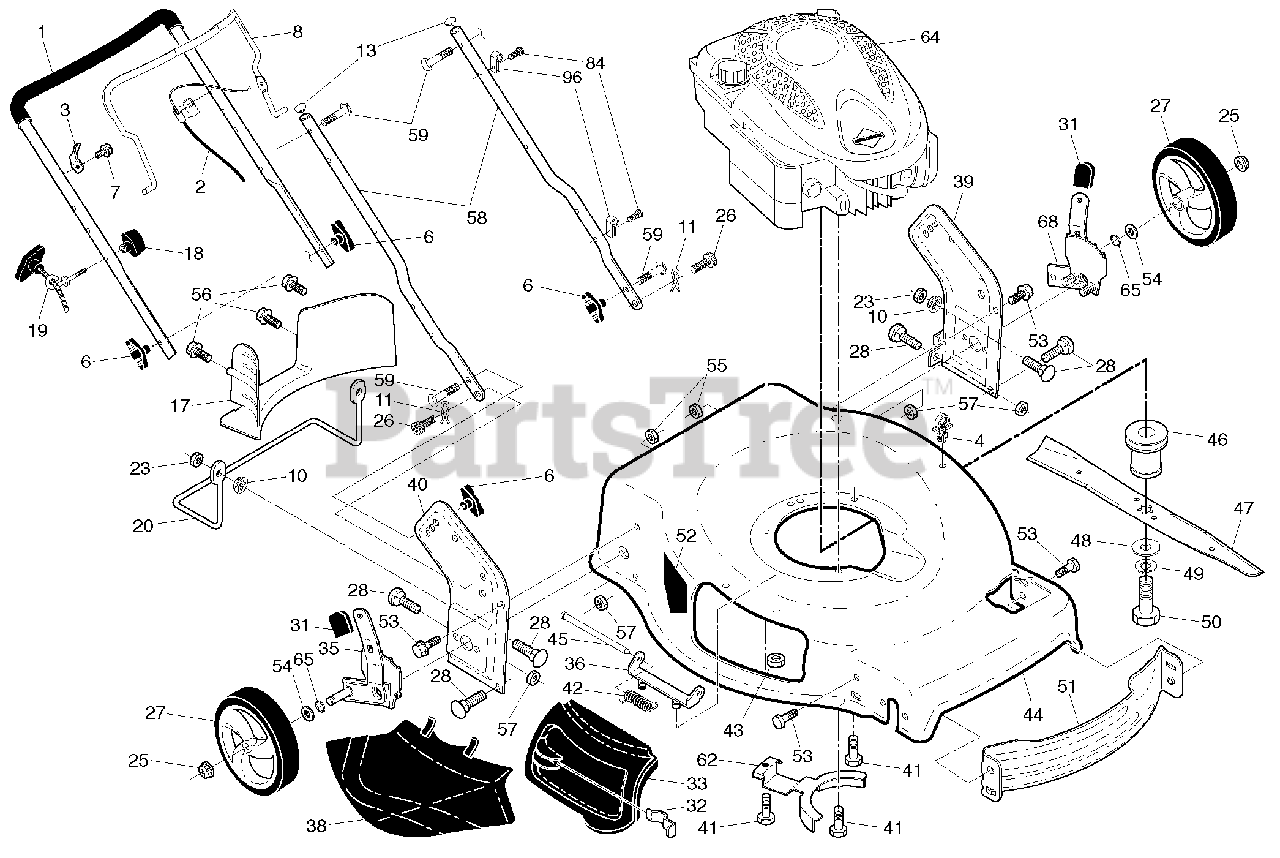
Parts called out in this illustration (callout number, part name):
1	HANDLE.ASM.UP.BS.PU/SS.GRP.479
2	Cable, MZR Fgd 22+ Ergo
3	BRACKET.UPSTOP.RT
4	PUSH CLIP
6	KNOB, DEFLECTOR
11	COTTER.HAIRPIN.DOOR/HANDLE.PIV
13	PLUG.PLASTIC.7/8".14-20.GAUGE
18	T-Knob, New Rope Guide
19	Rope Guide, Blk Zinc Chrom
23	LOCKNUT-FLANGE 5/16-18
25	NUT.HEX.FLANGE.3/8-16.LOCKNUT
26	SCREW,DOOR/HANDLE.PIVOT
28	Carriage Bolt, 5/16-18 X 5/8
31	SELECTOR KNOB
32	LATCH.DOOR.ZINC
35	Adjuster Assembly, 9Pos Lw Rr/Rgd
36	HINGE BRACKET ASSEMBLY
38	DEFLECTOR.CLIPPING.22.BLACK
39	Handle Bracket Assembly, LH 22+ Black
40	Handle Bracket Assembly, RH 22+ Black
41	BOLT 3/8-16X1-1/8
42	SPRING.TORSION
43	NUT.HEX.FLANGE.1/4
45	ROD.HINGE.21
46	Blade Adapter, 25mm Star
47	BLADE.22+4N1.2PIN.5STAR.
48	WASHER,HARDEN
49	LOCKWASHER
50	SCREW, HEX HD 3/8-24 X 1-3/8
52	DECAL.INTERNATIONL.CUTFINGER
53	BOLT.5/16HEX.WHS.HD
54	WASHER PM
55	NUT.HEX.FLANGE.1/4
56	SCREW.HX.13X.750
57	NUT.FLANGE.5/16
58	HANDLE.LOWER.22+.BT.2PC.BLK
59	BOLT, HANDLE 5/16-18X1.75
62	BRACKET.ENG/BELTKEEPER
65	O-RING..070X.487.NEOPRENE
68	Adjuster Assembly, 9Pos Lw Rl/Rgd Fr
84	FASTENER.PUSH.O.250X0.783
96	CLIP.CABLE.BLK
